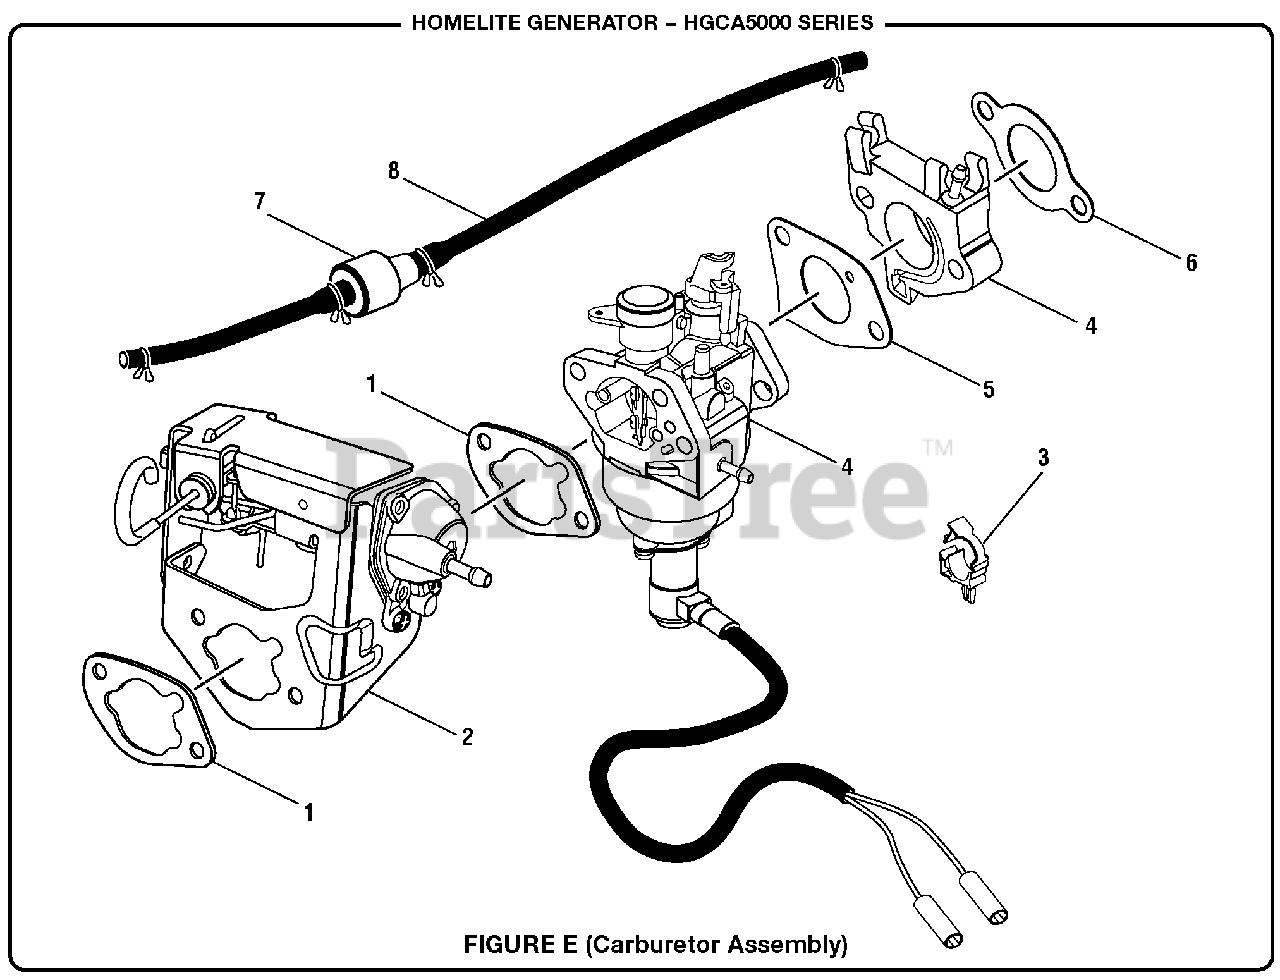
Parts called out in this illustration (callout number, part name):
1	Air Cleaner Gasket
2	Choke Assembly
3	Fuel Line Clamp (Holder)
4	Carburetor Assembly
5	Carburetor Gasket
6	Carburetor Inlet Gasket
7	Check Valve
8	Check Valve Assembly (Incl. Key No. 7)
